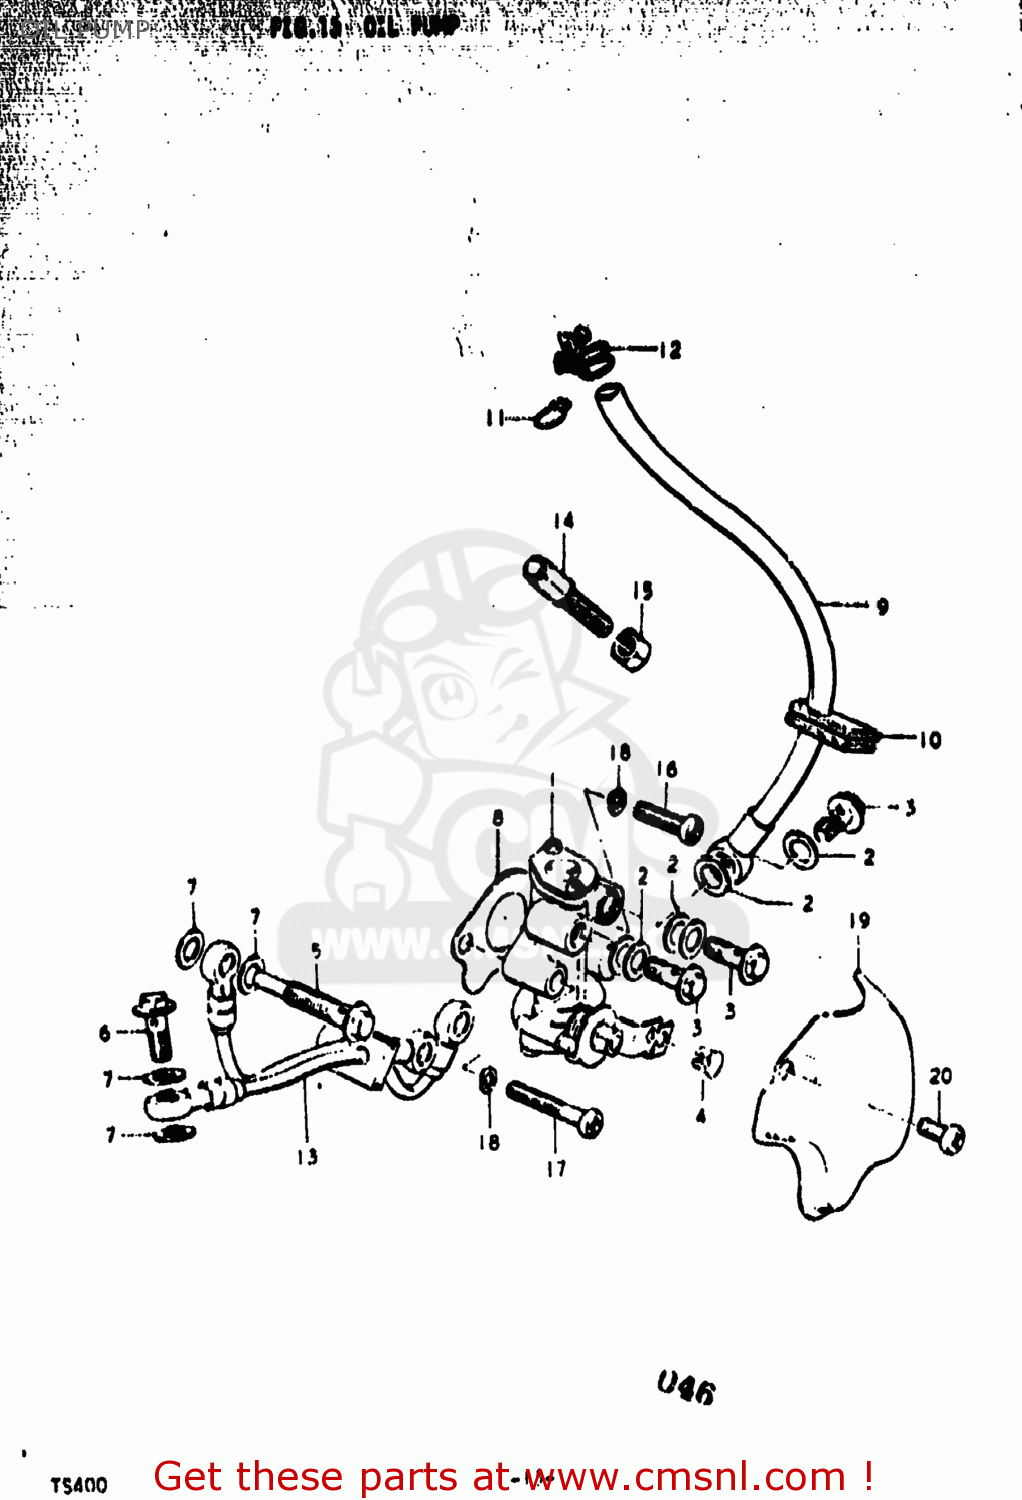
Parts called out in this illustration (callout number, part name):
1	PUMP ASSEMBLY,OIL
2	GASKET(6.2X11X1).2 (NAS)
3	UNION BOLT
4	TERMINAL,CABLE
5	UNION
6	UNION BOLT
7	GASKET(6.2X11X1).2 (NAS)
8	GASKET,OIL PUMP (MCA)
9	HOSE,OIL NO.1
10	GROMMET
11	CLIP
12	CLAMP
13	HOSE,OIL NO.2
14	BOLT
15	NUT
16	SCREW
17	SCREW
18	LOCK WASHER
19	CAP
20	SCREW
